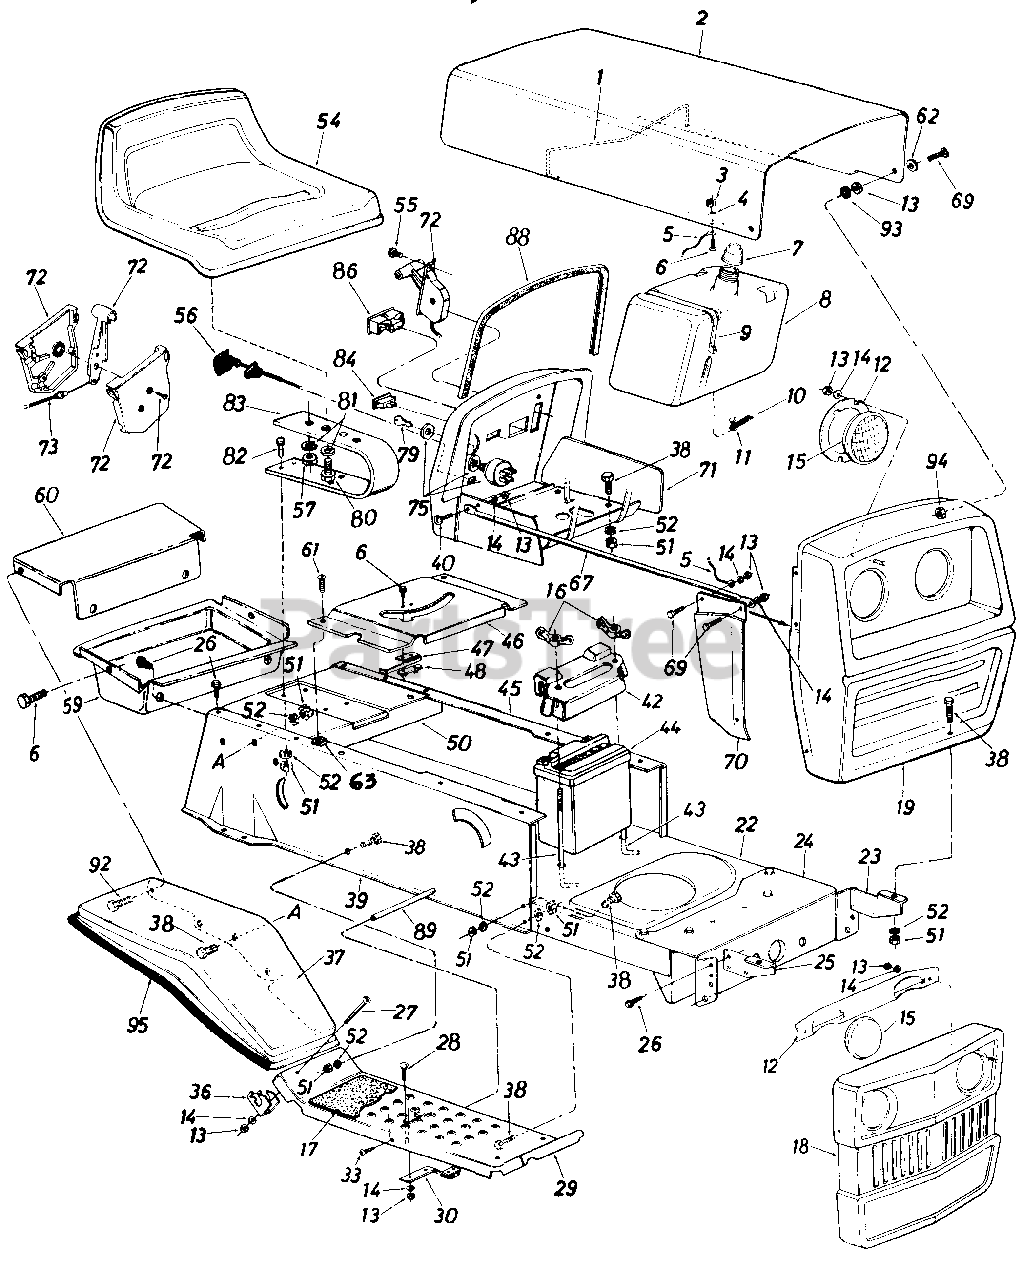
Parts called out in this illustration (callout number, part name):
1	Hood Spring
2	Hood
3	Hex Sems Nut #10-24 Thd.
4	Fl-Wash. .281" I.D. x .62" O.D. x .051
5	Hood Stop 7" Lg.
6	Truss Hd. Scr. #10-24 x 1/2" Lg.
7	Fuel Cap Gauge
8	Fuel Tank
9	Tie Strap
10	Fuel Line
11	Hose Clamp
12	Headlight Retainer
13	Hex Nut 1/4-20 Thd.
14	L-Wash. 1/4" I.D.
15	Headlight
16	Wing Nut 1/4-20 Thd.
17	Foot Pad
18	Grille Ass'y.
22	Lower Frame
23	Grille Mount Brkt.-L.H.
24	Front Pivot Brkt.
25	Grille Mount Brkt.-R.H.
26	Hex Wash. Hd. AB-Tap Scr. 5/16 x .75" Lg.
27	Truss Hd. Scr. 1/4-20 x 1.75" Lg.*
28	Carriage Bolt 1/4-20 x .62"Lg.
29	Running Board
30	Blade Brake Ass'y.
33	Truss Mach. Scr. 5/16-18 x .75" Lg.
36	Fender Clamp
39	R.H. Side Frame
40	Hex Bolt 1/4-20 x .62" Lg.
42	Battery Cover
43	Battery Hold Down Rod
44	12-V Battery
45	L.H. Side Frame
46	Transmission Panel
47	Reverse Safety Switch
48	Insulator Nut Plate
50	Hitch Plate
51	Hex Nut 5/16-18 Thd.
52	L-Wash. 5/16" I.D.
54	Seat Ass'y.
55	Truss Mach. AB-Tap Scr. #10 x .50" Lg.
56	Choke Control 29" Lg.
57	Hex Nut 1/2-13 Thd.
59	Tool Tray
62	Fl-Wash. .296 I.D. x .62 O.D.
63	Speed Nut #10Z
67	Grille Support Rod
69	Truss Hd. Scr. 1/4-20 x .75" Lg.*
70	R.H.-Grille Side Panel
71	Dash Panel Ass'y.
72	Throttle Control Box Ass'y.
73	Throttle Control Wire
75	Ignition Switch
79	Ignition Key
80	Hex Bolt 1/2-13 x 1.00" Lg.
81	L-Wash. 1/2" I.D.
82	Hex Bolt 5/16-18 x 1.00" Lg.*
83	Seat Spring
84	Light Switch
86	Ammeter
88	Molding Strip 27" Lg.
89	Running Board Rod
92	Thread Rolling Scr. 1/4-20 x .50" Lg.
93	Rubber Wash. 1/2" I.D. x 1.0 O.D. x .25
94	Hex Sems Ins. L-Nut 1/4-20 Thd.
95	Trim Strip
